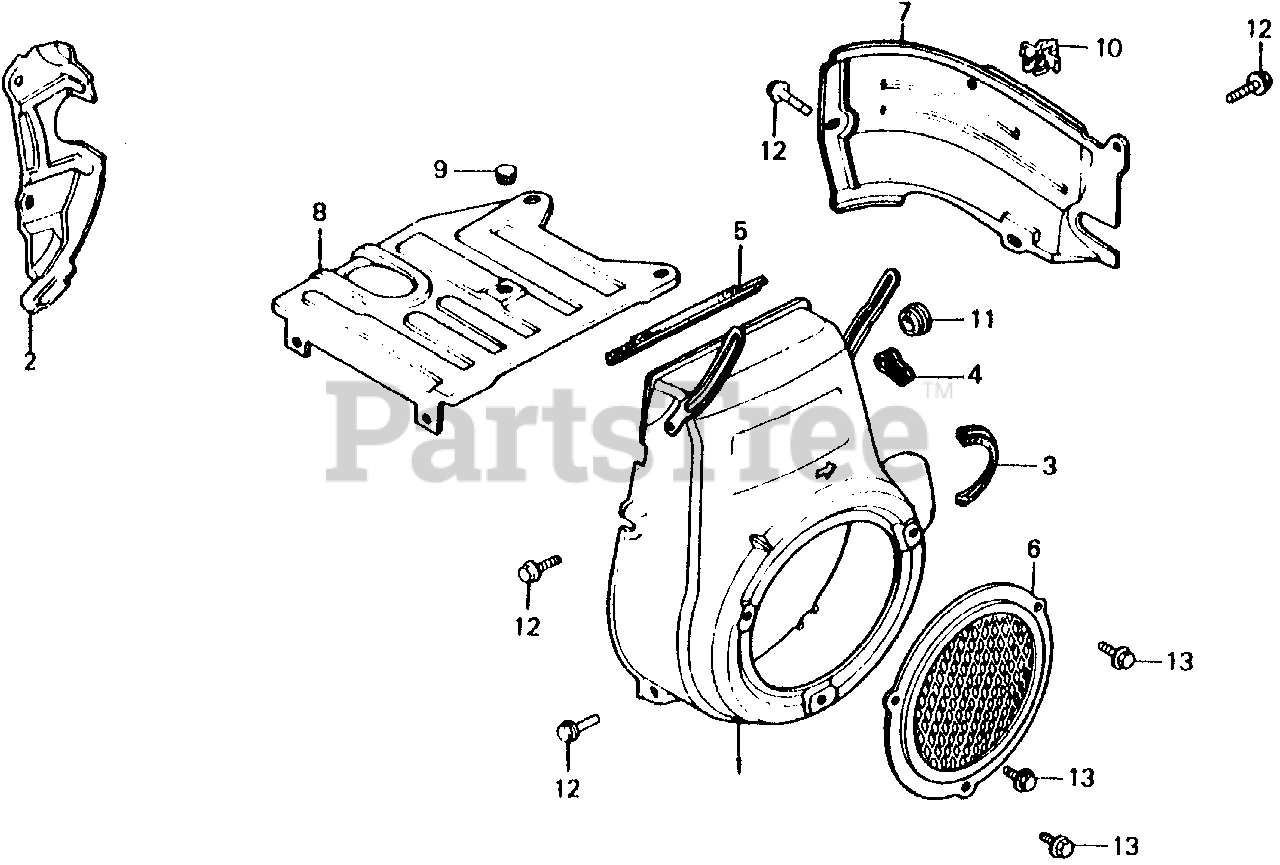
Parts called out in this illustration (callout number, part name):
1	COVER, FAN *NH116M* (URBAN SILVER METALLIC)
2	PLATE, SIDE
3	SEAL A, FAN COVER
4	GROMMET, FAN COVER
5	SEAL B, FAN COVER
6	PROTECTOR, FAN COVER *NH116M* (URBAN SILVER METALLIC)
8	COVER, TOP *NH116M* (URBAN SILVER METALLIC)
9	GROMMET, COVER
10	CLIP, IGNITION WIRE (8MM)
11	GROMMET, DRAIN HOLE
12	BOLT, FLANGE (6X12) (CT200)
13	BOLT, FLANGE (6X10)
